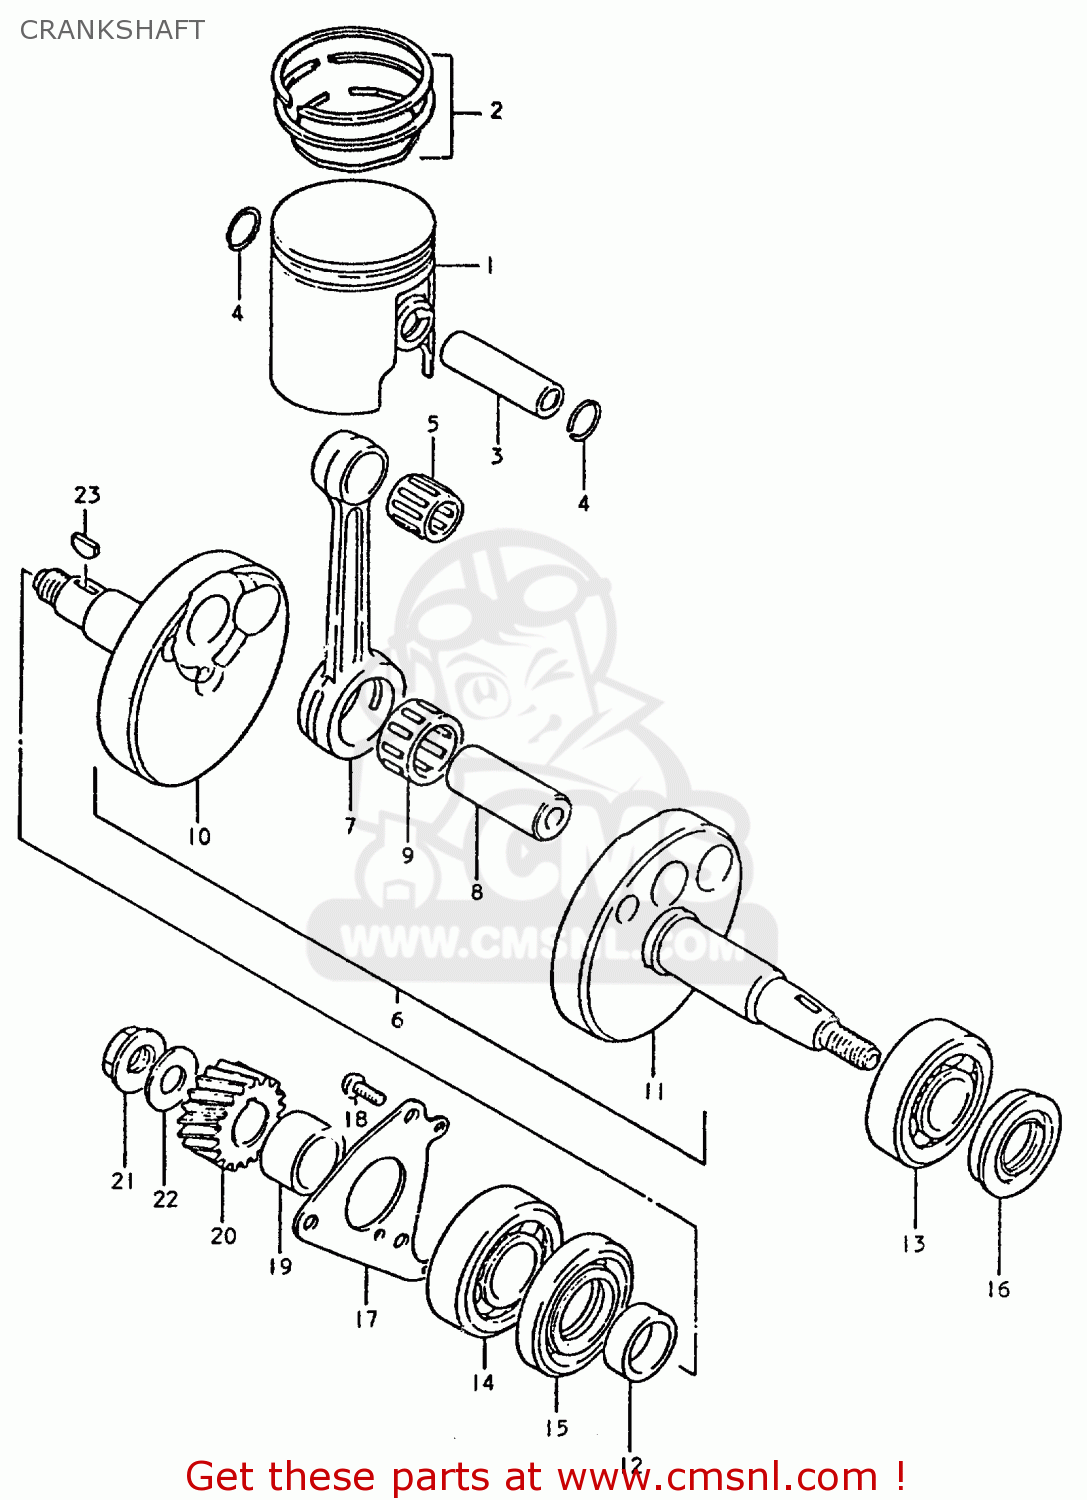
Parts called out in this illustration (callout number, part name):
1	PISTON
2	RING SET,PISTON
3	PIN,PISTON
4	RING,SNAP
5	BEARING
6	CRANKSHAFT ASSEMBLY
7	CONNECTING ROD
8	PIN,CRANK
9	BEARING
10	CRANKSHAFT,RIGHT
11	CRANKSHAFT,LEFT
12	SPACER(20X26X9)
13	BEARING
14	BEARING
15	OIL SEAL
16	SEAL,OIL(19.6X37X8)
17	RETAINER,CRANKSHAFT BEARING,R
18	SCREW 6X12
19	SPACER(20X26X14)
20	GEAR,PRIMARY DRIVE NO.19
21	NUT
22	WASHER
23	KEY
